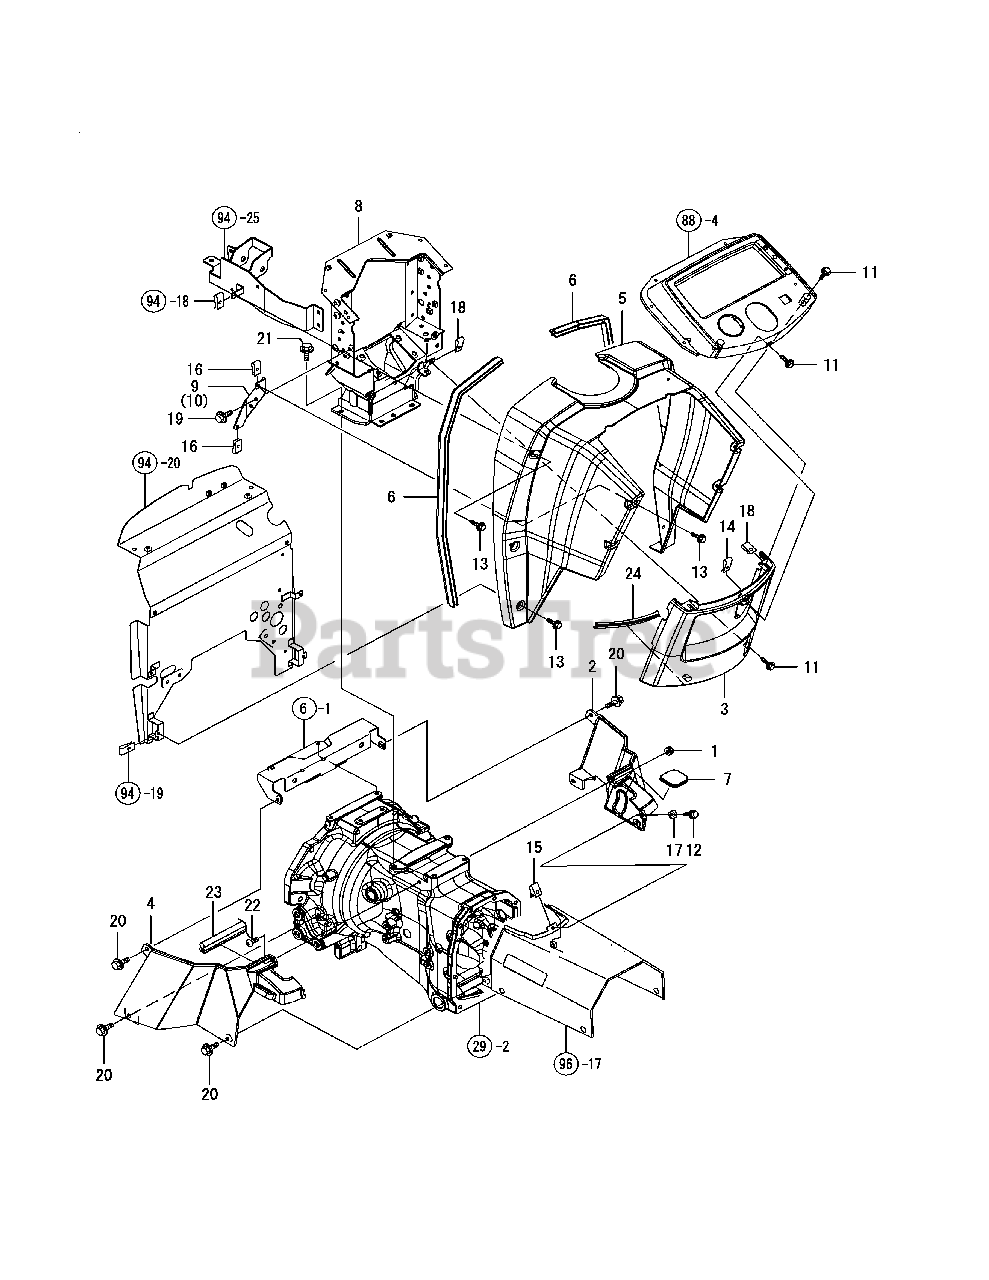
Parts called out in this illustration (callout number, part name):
1	NUT W/WASHER 6
2	COVER, LOWER R.H
4	COVER, LOWER L.H
7	GROMMET, LOWER COVER
8	SUPPORT, DASHBOARD
9	SUPPORT, COVER L.H.
10	SUPPORT, COVER R.H.
14	NUT, M5
15	NUT, M5
16	NUT, M5
19	BOLT M 8X 12 PLATED
20	BOLT M 8X 16 PLATED
21	BOLT M10X 20 PLATED
23	WEATHER-STRIP, 550
24	SEAL, DASHBOARD COVER
